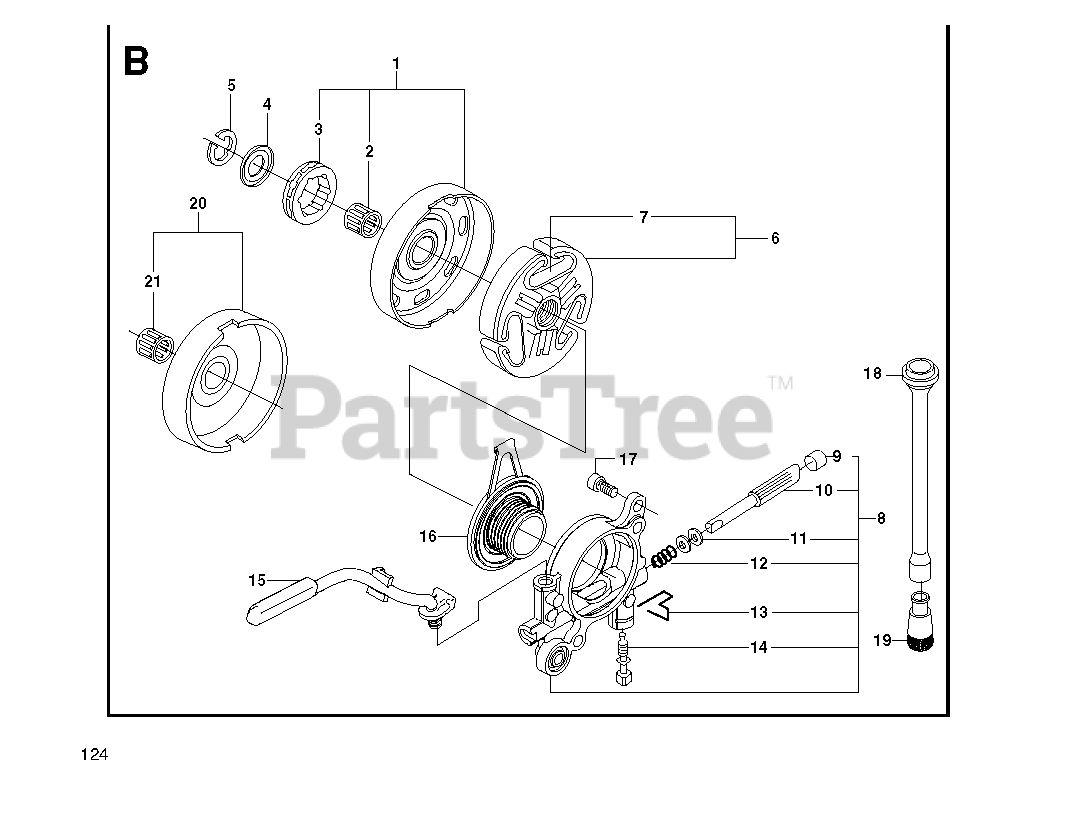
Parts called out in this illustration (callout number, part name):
1	CLUTCH DRUM ASSY
2	CLUTCH DRUM BEARING
3	68210 RIMSPROCKET
3	Power Mate Rim
5	RETAINING RING
6	CLUTCH
8	OIL PUMP
10	PUMP PISTON
11	WASHER 6.1X9
13	SPRING CLIP
19	OIL SCREEN
20	CLUTCH DRUM
21	CLUTCH DRUM BEARING
